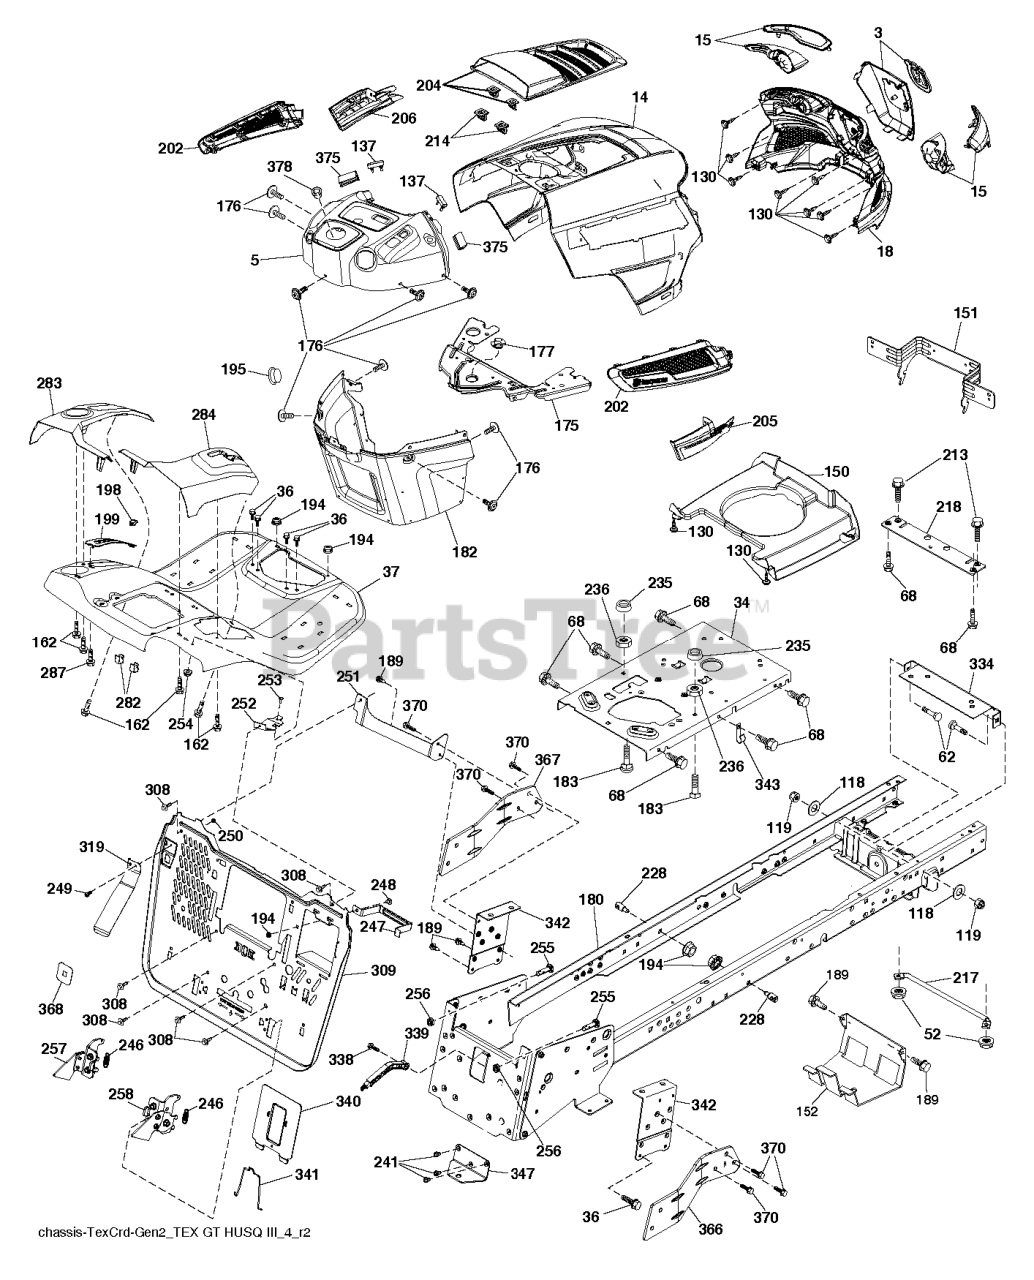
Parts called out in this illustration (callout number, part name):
5	DASHBOARD.UPPER.ASM.GT2.X498
14	HOOD.ASM.HUSQVARNA.GT.TEX.ORAN
15	Service Kit
36	SCREW 5/16"
37	FENDER.TEX.SRD.CRD.BASE
118	WASHER
137	BUMPER DASH
150	AIR.DUCT.GTV.BLACK
151	BRACKET.PIVOT.HOOD.GT.HUSQ.II
152	SHIELD.BROWNING.W/TEX
175	PLATE.PNT.CROSSMEMBER.HUSQ/PRE
176	SCREW.#10-24X5/8.RN.QU
177	BUSHING STEERING
180	CHASSIS WELDMENT.CRD2.BKP_BLTS
182	DASH LOWER.HUSQ.PRED NO CRUISE
189	SCREW
195	PLUG.HOLE.DASH.LOWER.12V.BLK
198	INDICATOR.DECK.LIFT.RED
199	PLATE DECK LIFT
202	Vents
205	SIDE.TRIM.RH.GT.HUSQ.II
206	SIDE.TRIM.LH.GT.HUSQ.II.GRAY
213	SCREW HEXAGON HEAD SCREW 5/16-
214	CLIP.RETAINER.TINNER.
217	ROD.PIVOT.HOOD
218	X-PIECE.HOOD.STOP.NON/
228	STUD.FASTNER.W/ANTI-ROTATE
236	NUT.CENTERLOCK.5/16-
246	SPRING.LTCH.BGR.GEN2.5.CRD.TEX
247	STRAP.BATTERY.TCRD.GEN2.5X431
248	BOLT.CARR.5/16-18X1/2
249	SCREW.BUTTONHD.10-24X1/2.(2 2)
251	BRACKET.PNT.LH.SUPP.BKPLT.EDIP
252	BRACKET.PNT.RH.SUPP.BKPLT.EDIP
253	BOLT CUP HEAD SQUARE NECK BOLT
254	NUT T
257	LATCH.ASM.BGR.LH.GEN2.5.STMPD
258	LATCH.ASM.BGR.RH.GEN2.5.STMPD
282	CLIP.RETAINER.CONSOLE.LT.HUSQ
283	CONSOLE.DECKLIFT.CRDII.498
284	CONSOLE.PEDAL.HYDRO
287	SCREW 1/4X20
308	BOLT.5/16-18UNCX3/4 W/SEMS.BLK
309	BACKPLATE.TEXCRD2.5.BAGGER.479
319	LEVER.PRSNC.BGR.TEX.CRD.GEN2.1
334	BRACKET.ENGINE
339	LEVER LEVER BAGGER
340	BATTERY.DOOR.TCRD.GEN2.5.MS479
341	LATCH.BATTERY.DOOR.TCRD
342	SUPPORT.PNT.FENDER.CRD.TEX
343	CLIP CLIP
347	HITCH HITCH TOW TEX CRD GEN 2
366	BRACKET.RH.FRONT.BAGGER.BLACK
367	BRACKET.LH.FRONT.BAGGER.BLACK
368	FULL.LEVER.BAGGER.TEX.CRD
370	SCREW 3/8-16X1
375	BUMPER CLIP-ON. DASH 1"
378	BUSHING FLANGE; PLASTIC
